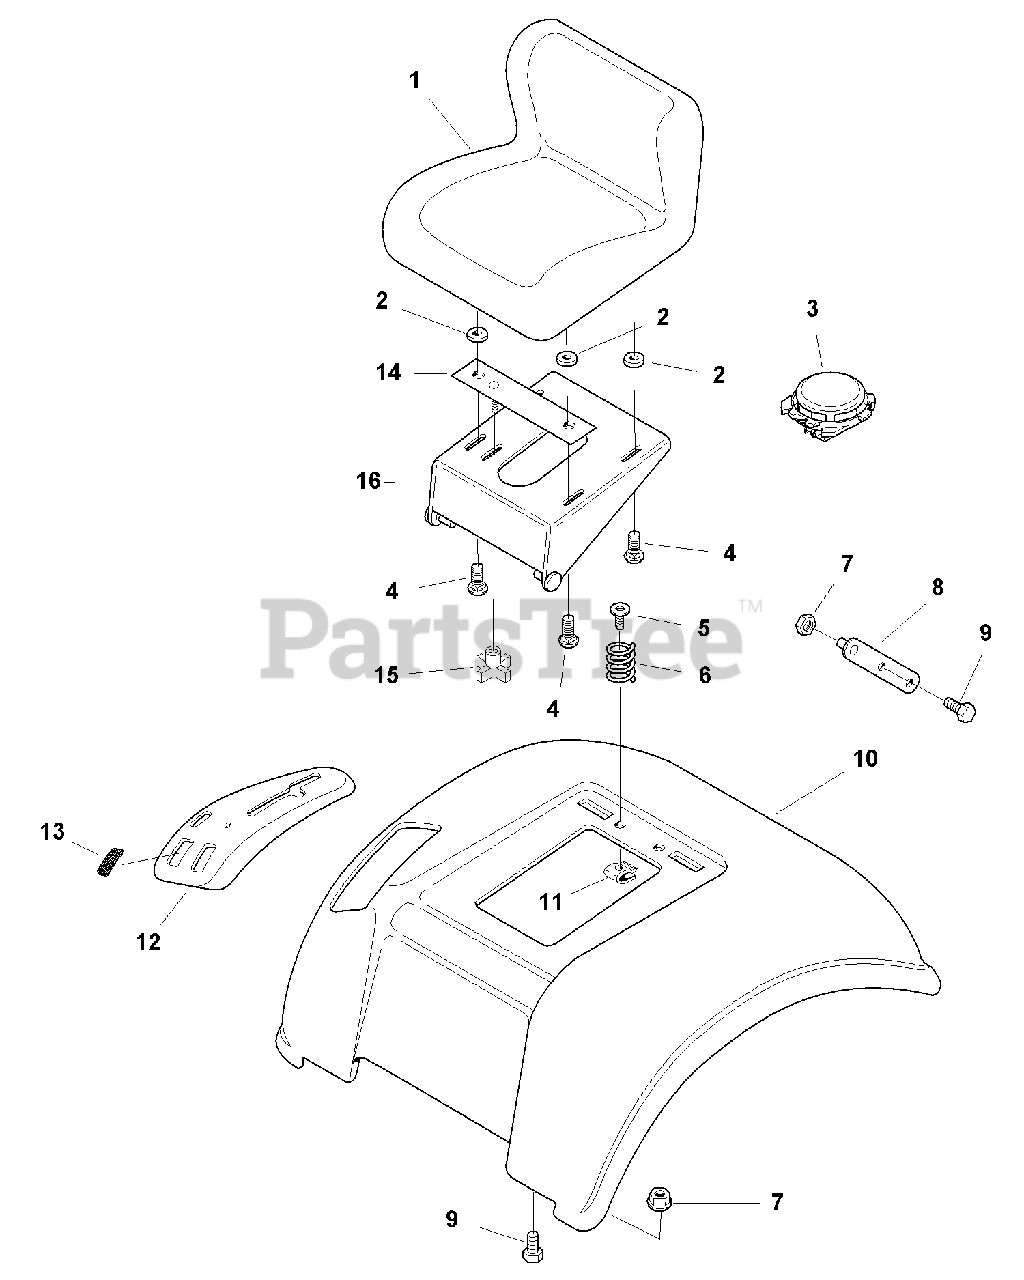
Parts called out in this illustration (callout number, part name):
2	WASHER
3	SWITCH, Seat
4	CARRIAGE BOLT, 5/16-18 x 3/4
5	SCREW, Flat Head, 5/16-18 x 1-1/4
6	SPRING, Compression
7	NUT, Hex Head Whiz Lock, 5/16-18
9	CAPSCREW, Hex Head, 5/16-18 x 3/4
10	DECK, Seat, (Orange)
10	DECK, Seat, (Red)
11	NUT, Speed 5/16-18
14	CLAMP & SCREW ASSEMBLY
16	SUPPORT & PIN ASSEMBLY
